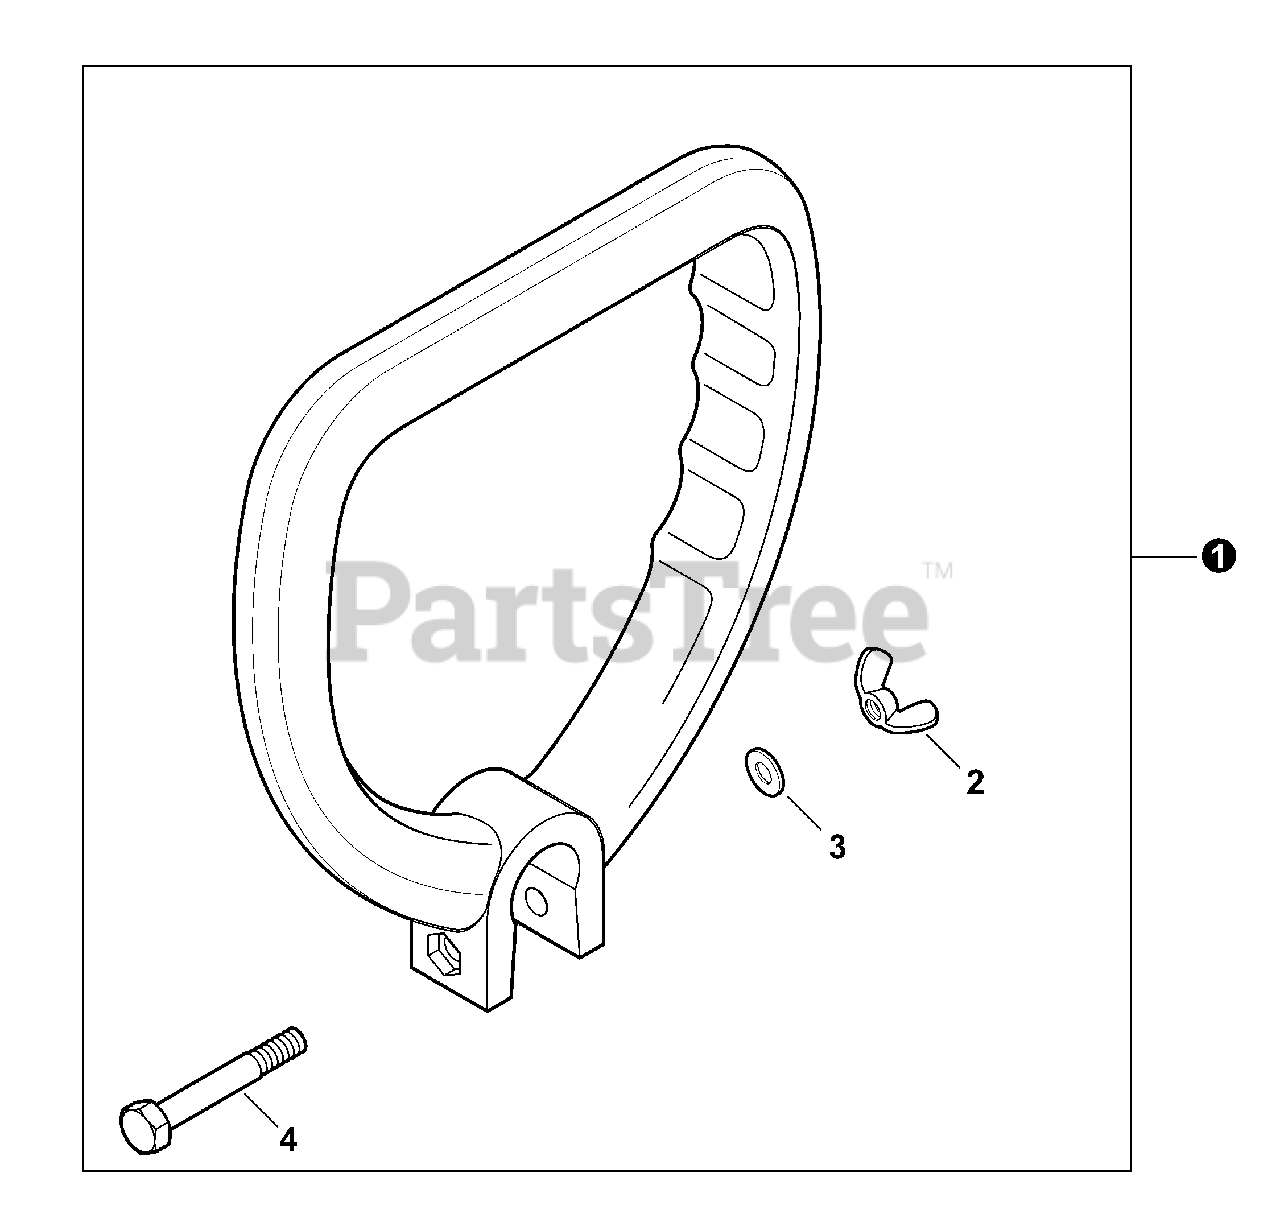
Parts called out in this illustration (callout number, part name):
1	HANDLE ASSY
2	NUT, WING 1/4"-20
3	WASHER, 1/4"
4	BOLT 6×45
